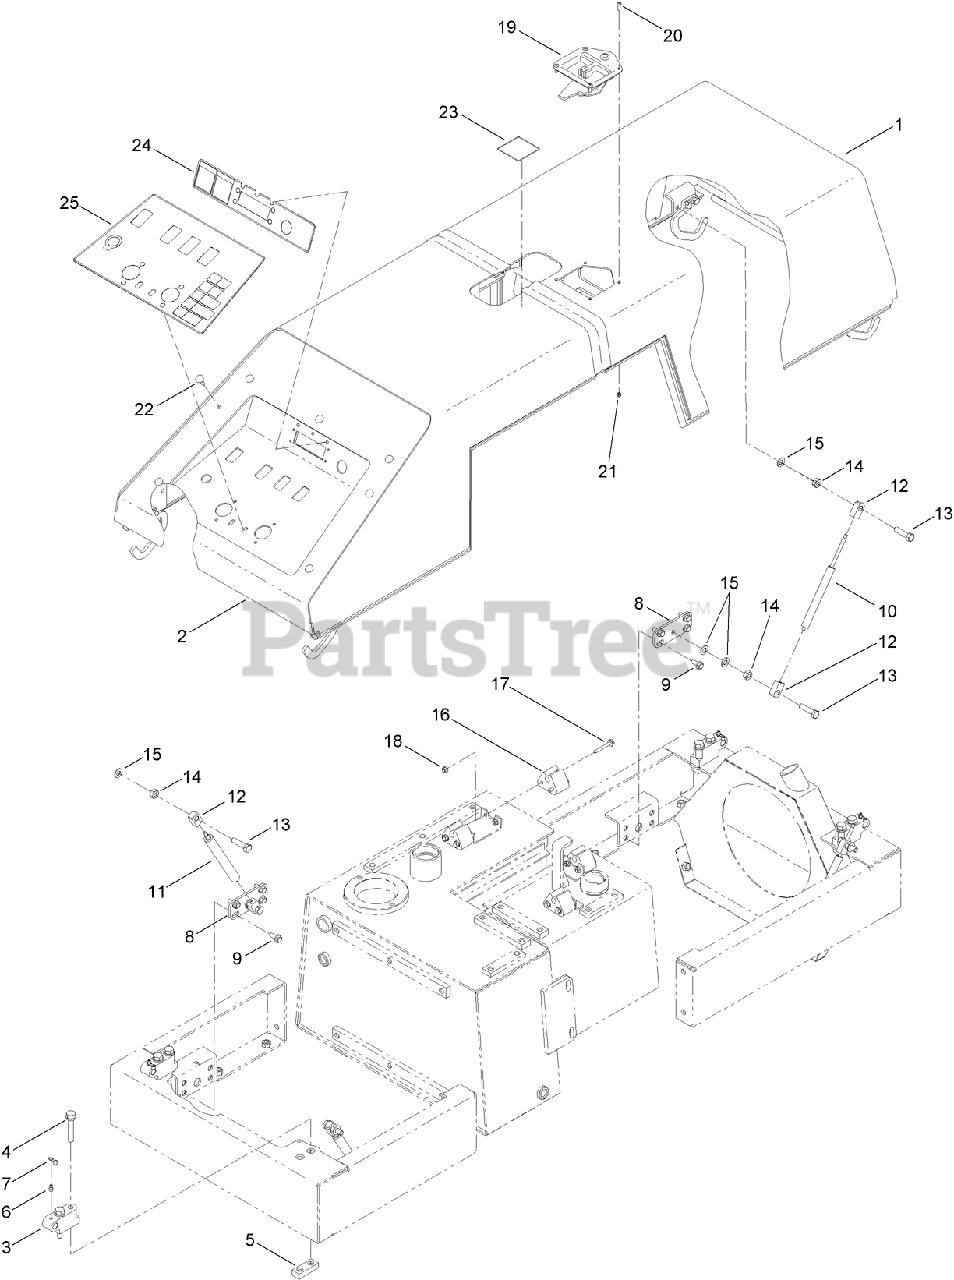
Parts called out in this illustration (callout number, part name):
1	HOOD-ENGINE
2	HOOD-OPERATOR
3	BLOCK-HINGE, HOOD
4	SCREW-HHF
5	PLATE-HINGE, NUT
6	FITTING-GREASE
7	CAP-PLUG
8	PLATE-MOUNTING, GAS SPRING
9	SCREW
10	SPRING-GAS
11	SPRING-GAS
12	ROD-END, GAS SPRING
13	SCREW-HH
14	NUT-HEX
15	WASHER-FLAT
16	LATCH-CLIP, HOOD
17	SCREW-HHF
18	NUT-HF
19	LOCK, T-HANDLE
20	SCREW-HSBH
22	CLIP-ARROW, NYLON
23	DECAL-LIFT HERE
24	DECAL-READOUT, IGNITION
25	DECAL-CONSOLE
